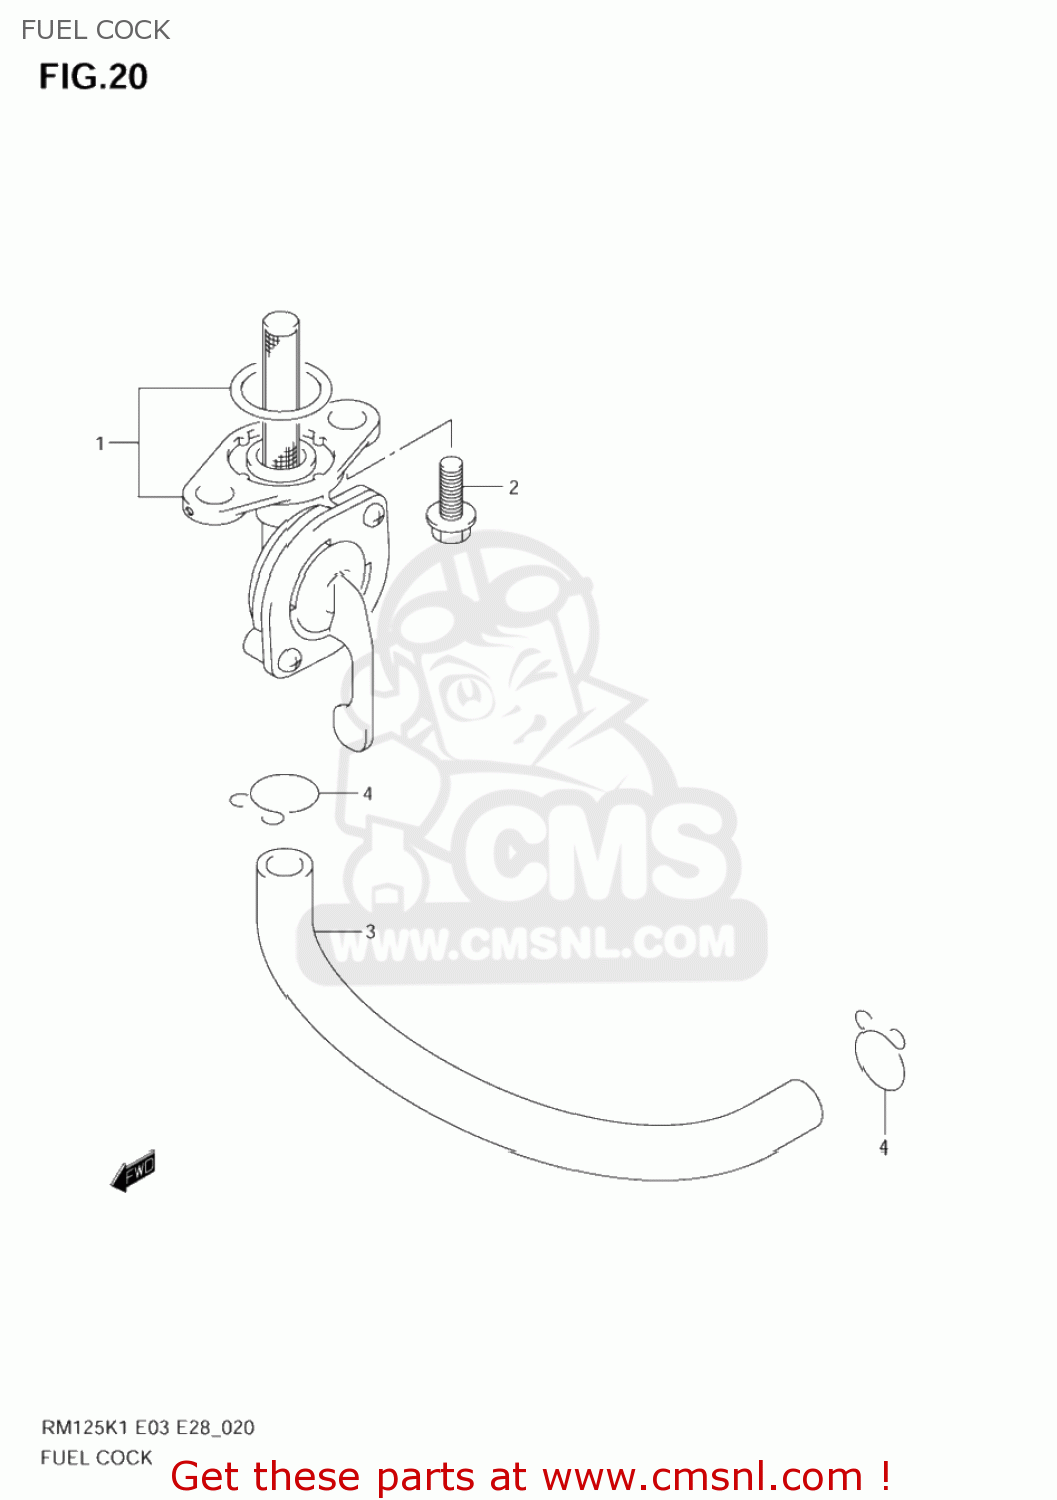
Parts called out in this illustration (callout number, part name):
1	COCK ASSY,FUEL
2	BOLT
3	HOSE,FUEL
4	CLIP
